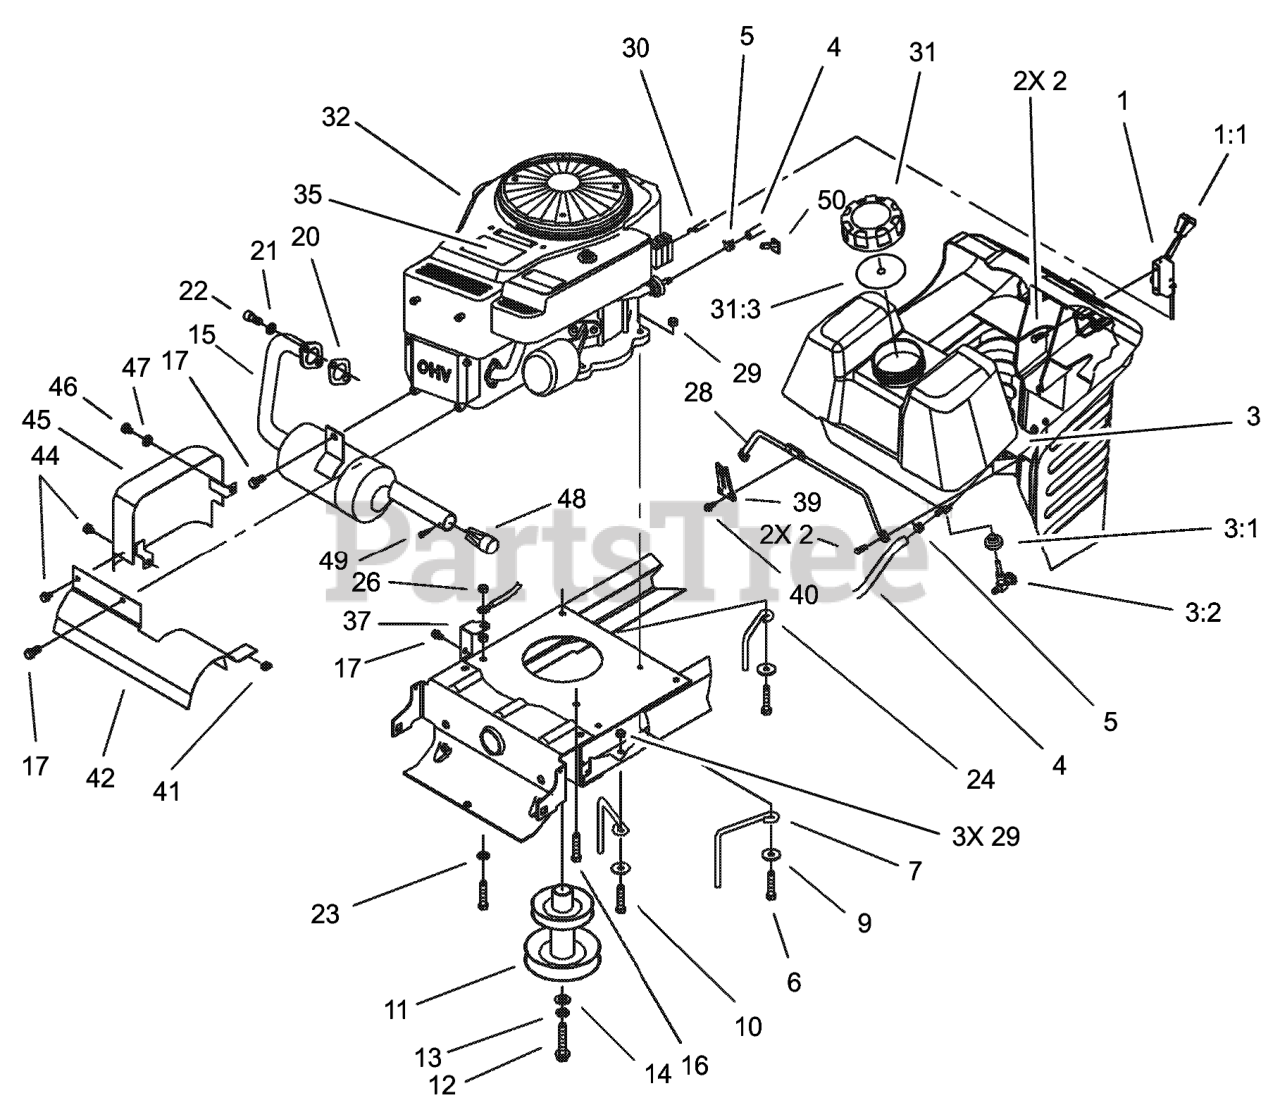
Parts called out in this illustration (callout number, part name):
1	THROTTLE CONTROL ASM
2	SCREW-SPECIAL
3	GAS TANK ASM
3:1	BUSHING
3:2	VALVE-FUEL
4	HOSE-FUEL
5	CLAMP-HOSE
6	SCREW-HH
7	GUIDE-BELT, ENGINE
9	WASHER-PIVOT
10	SCREW-HH
11	Pulley-Engine
12	SCREW-HH
13	WASHER-LOCK
14	WASHER-FLAT
15	MUFFLER
16	SCREW-HWH, TAPTITE
17	SCREW-HWH
20	GASKET-EXHAUST
21	WASHER-LOCK
22	SCREW-HSH
23	WASHER-LOCK
24	GUIDE-BELT, RH
26	NUT-KEPS
28	ROD-TANK, GAS
29	NUT-LOCK, NI
30	THROTTLE CABLE ASM
31	GAS CAP ASM
31:3	GASKET-CAP, GAS
35	Decal-Engine, 17hp
37	BRACKET-GROUND
39	LATCH-HOOD
40	SCREW-HWH
41	CLIP-TINNERMAN
42	SHIELD-MUFFLER
44	SCREW-HWHTF
45	HEAT SHIELD ASM
46	SCREW-HH
47	WASHER-LOCK
48	SCREEN-SILENCER, EXHAUST
49	SCREW-THD FORM, HWH
50	REDUCER-THROTTLE, RPM
